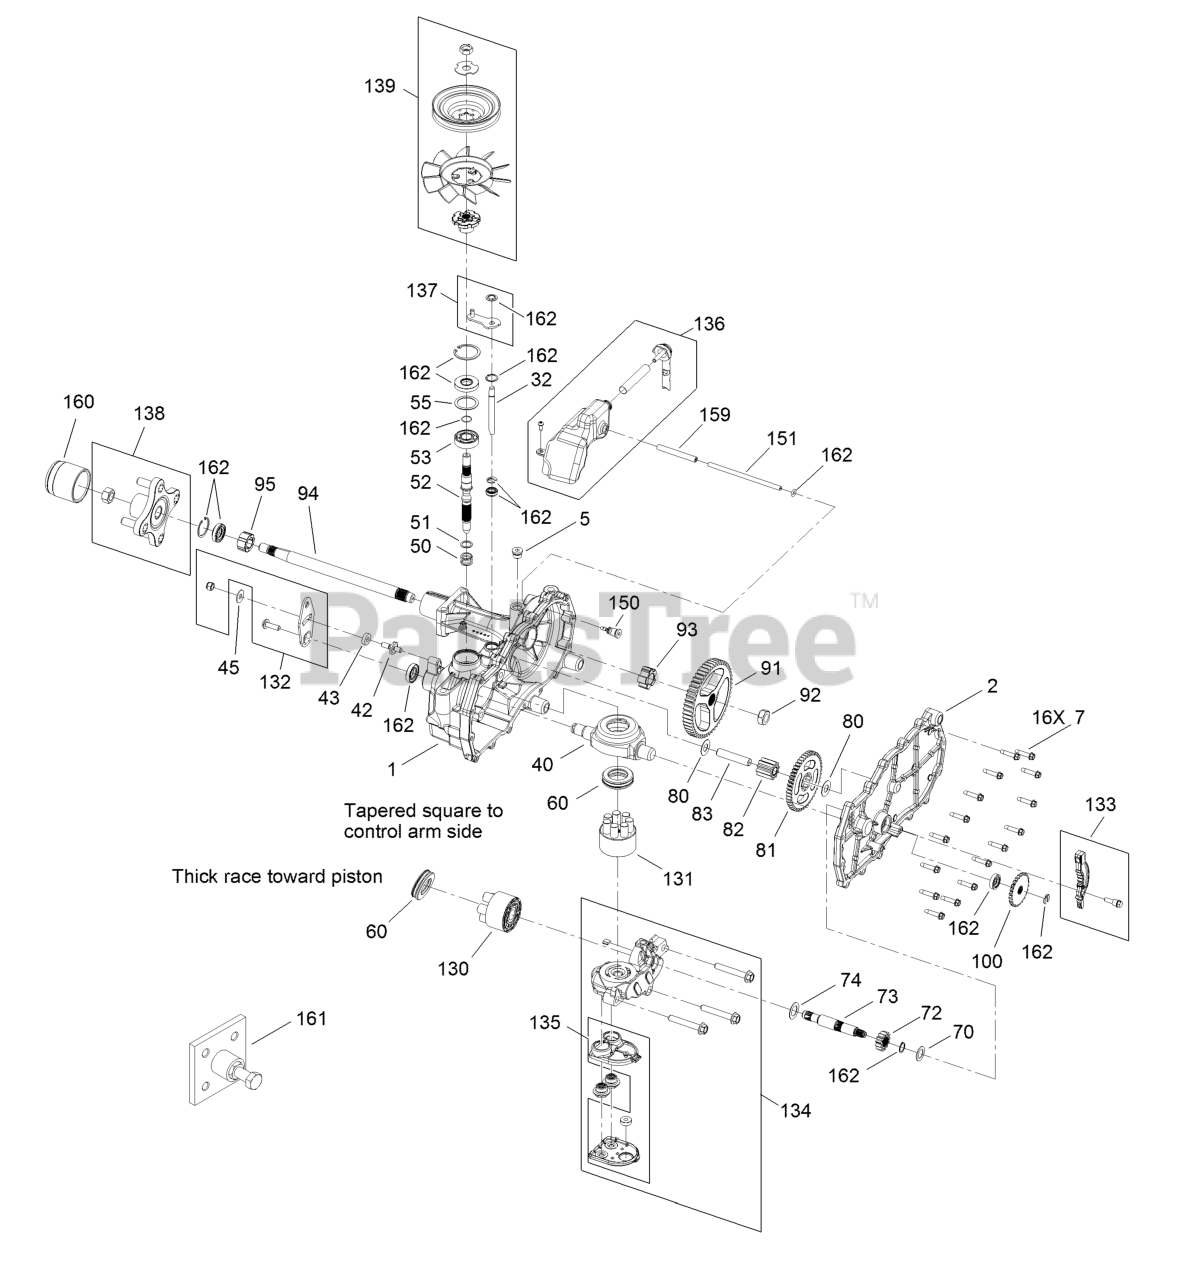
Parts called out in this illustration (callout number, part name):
1	Main Housing ASM
2	Housing Side Kit
5	Plug-Thread, Straight
7	Screw-HHF
13	Sealant
32	Rod-Bypass
40	Swashplate-Trunnion
43	Puck-Friction
50	Spring-Compression
52	Shaft-Input
53	Bearing-Ball
60	Bearing-Thrust
70	Washer-Flat
72	Gear-Pinnion, 13T
73	Shaft-Motor
80	Washer
81	Gear-10T/48T
82	Gear-Jackshaft, 10T
83	Pin-Jackshaft
91	Gear-Bull
93	Bushing-Inboard
94	Shaft-Axle
95	Bearing-Sleeve
100	Disc-Brake, Cog
130	Cylinder Block Kit
131	Pump Block ASM
132	Control Arm Kit
133	Brake Arm Kit
134	Center Section Filter Kit
135	Filter Kit
136	RH Expansion Tank Kit
137	Bypass Kit
138	Hub Kit
139	Fan Pulley Kit
150	Fitting-SAE
159	Case-Tube
160	Cap-Axle
161	Puller-Hub, 4 Bolt
162	Seal And Ring Kit
